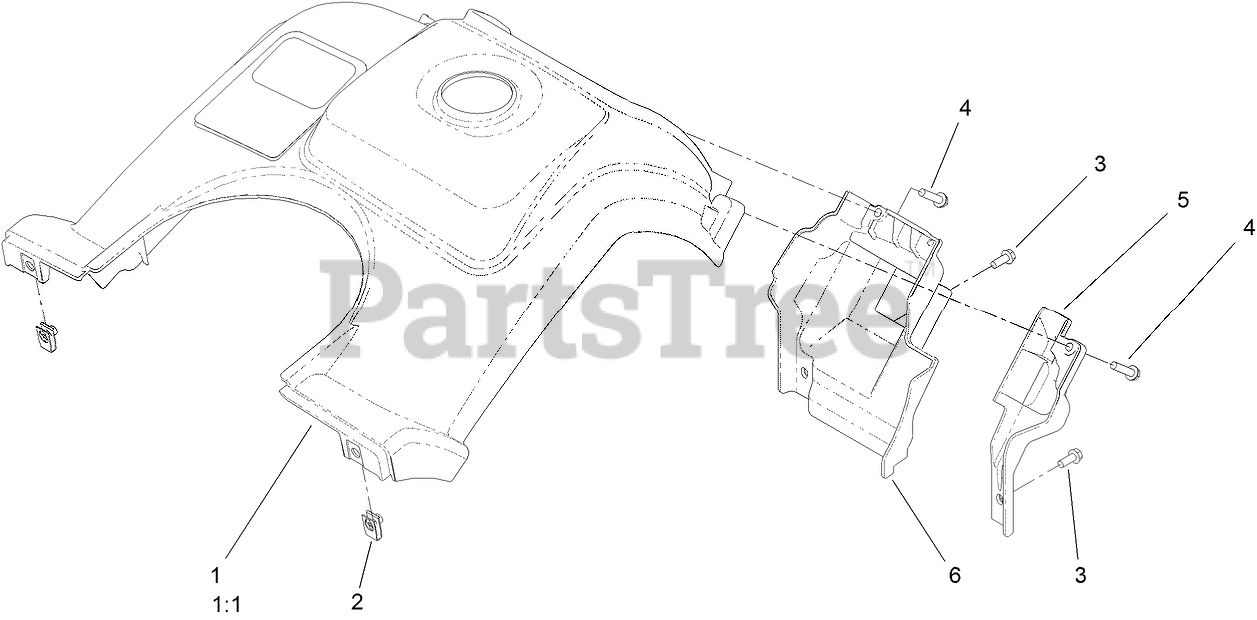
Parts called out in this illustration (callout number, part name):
1	SHROUD ASM
1:1	SHROUD
3	SCREW-HWH
4	SCREW-PLASTIC,HWH
5	SHROUD-LOWER, LH
6	SHROUD-LOWER, RH
